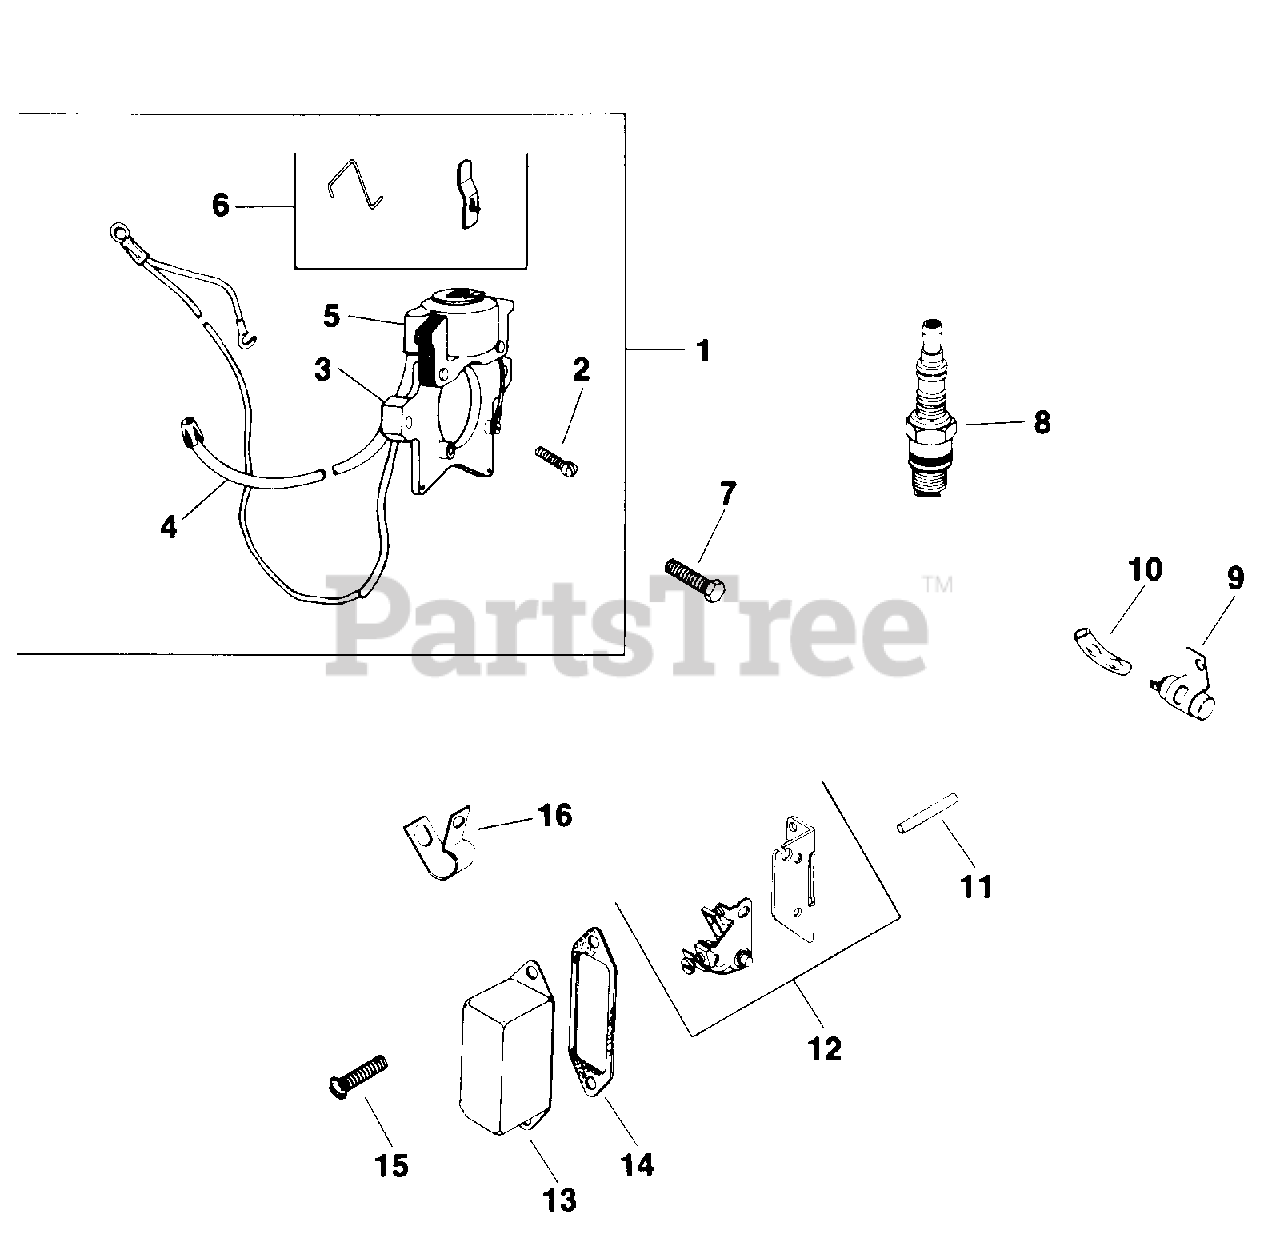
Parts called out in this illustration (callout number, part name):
1	Stator Assembly (Includes 2-6)
3	Core & Plate
6	Kit, Coil Clip
7	Screw, H.C. 1/4-20 x 1
10	Sleeve, Insulating
11	Rod, Breaker
13	Cover, Breaker
14	Gasket, Cover
15	Screw, F.H.M. 10-24 x 3/8
16	Clip, Hi-Tension
